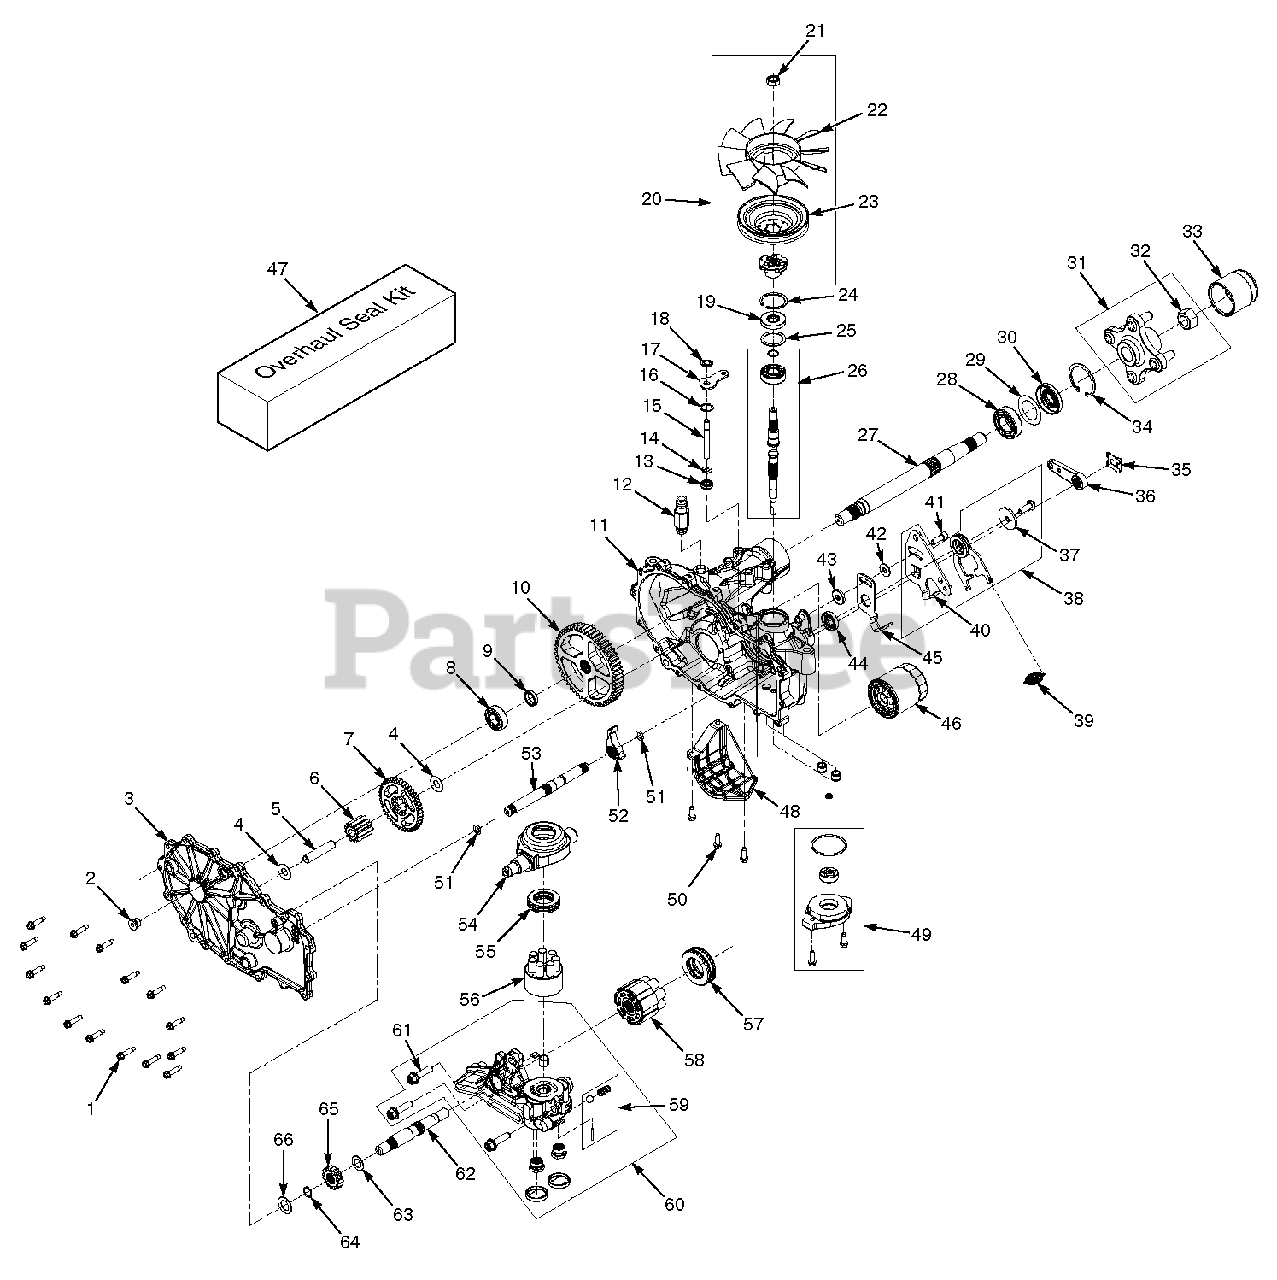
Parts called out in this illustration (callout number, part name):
1	Bolt, Hex Head 1/4-20 x 1-1/8"
2	Plug, 9/16-18
3	Kit, Side Cover
4	Washer, .5 x 1.0 x .03
5	Jackshaft Pin
6	Gear, 11T
7	Gear, 43T
8	Bearing, Ball .75 x 40 x 12
9	Spacer, .75 x 1.32 x .257
10	Gear, 54T
11	Kit, Housing
12	Fitting, Transmission
13	Seal, Lip .375 x .75 x .25
14	Ring, .Retaining .375 External
15	Rod, By-Pass
16	Ring, Retaining .750 Internal
17	Arm, By-Pass
18	Ring, .Retaining .375 External
19	Seal, Lip 17 x 40 x 7
20	Kit, Fan & Pulley
21	Nut, Hex Locking 1/2-20
23	Pulley
24	Ring, Retaining 2.06 Internal
25	Washer, 1.23 x 1.56 x .04
26	Kit, Shaft, Input
27	Kit, Shaft, Axle
28	Bearing, Ball 1.0 x 52 x 15 Open
29	Spacer, 1.355 x 2.035 x .021
30	Seal, Lip TC4 1.0 x 2.06 x .38
31	Hub Kit
32	Nut, Hex Locking
33	Cap, Axle
34	Ring, Retaining 2.06 Internal
35	Clip, Retaining
36	Handle, Brake
37	Washer, .343 x 1.5 x .062
38	Kit, RTN Assembly
39	Spring, RTN
40	Arm, Control
41	Bolt, 5/16-24 x 7/8" Patch
42	Washer, .34 x .88 x .06
43	Spacer, .320 x 1.005 x .150
44	Seal, Lip 12 x 32 x 7
45	Arm, Neutral
46	Filter
47	Seal Kit
48	Filter Guard
49	Kit, Charge Pump
50	Bolt, 1/4-20 x 3/4"
51	O-Ring
52	Pawl, Brake
53	Shaft, Brake
54	Trunnion Swashplate
55	Thrust Bearing
56	Kit, Cylinder Block
57	Thrust Bearing
58	Kit, Motor Cylinder Block
59	Kit, Charge Relief
60	Kit, Center Section
61	Bolt, Hex Head 3/8-16 x 1-1/2" Patch
62	Shaft, Motor
63	Washer, .72 x 1.16 x .04
64	Ring, Retaining
65	Gear, 16T
66	Washer, .63 x 1.0 x .05
